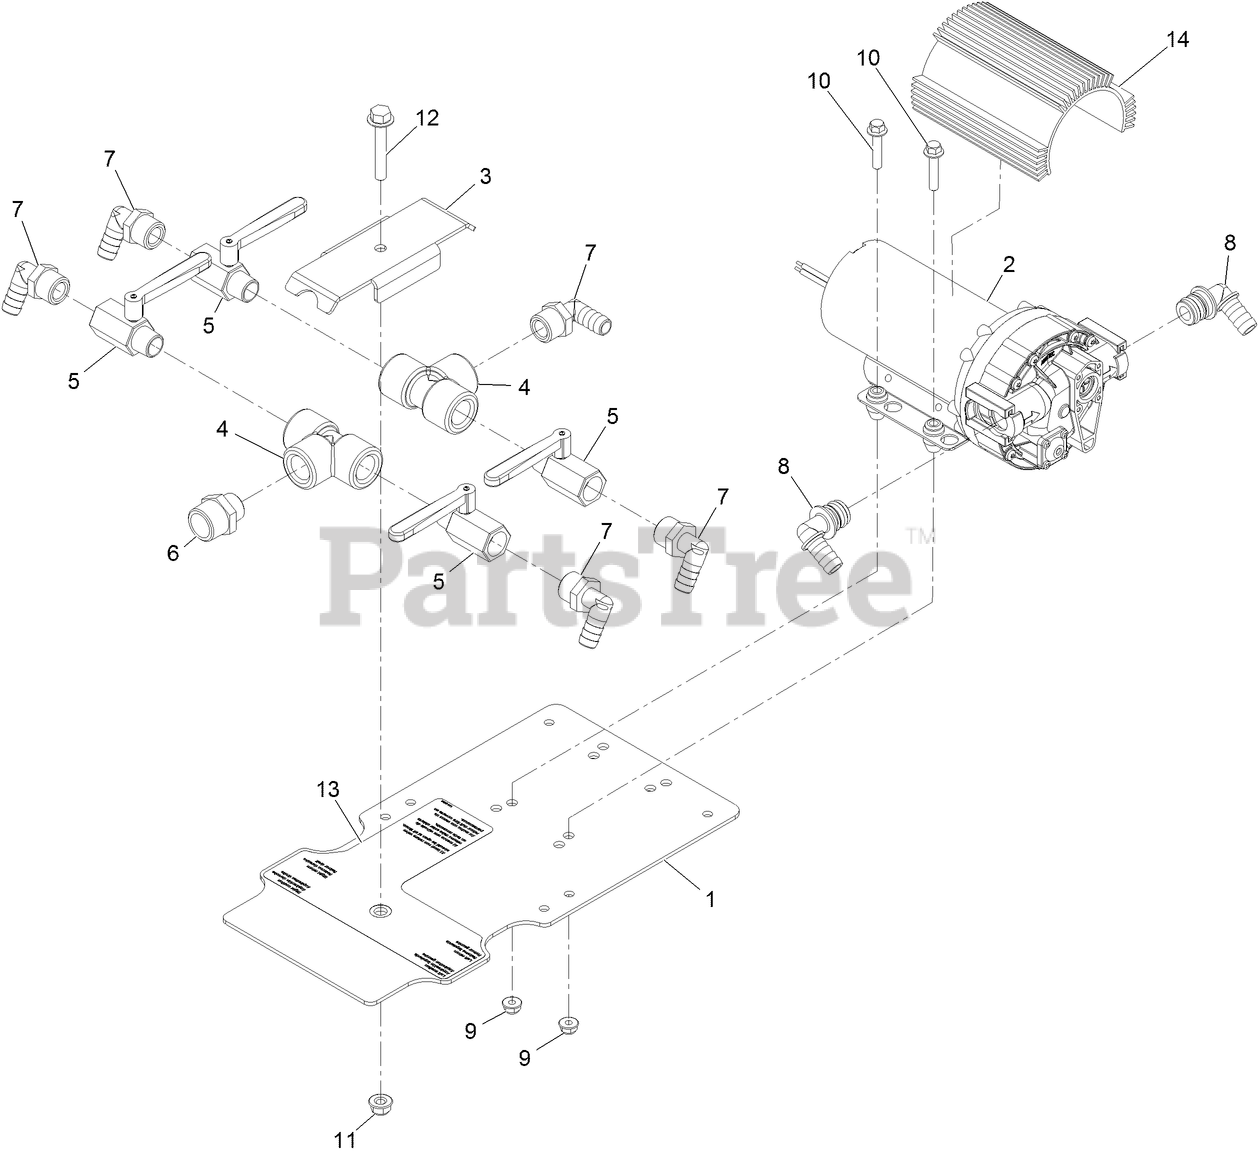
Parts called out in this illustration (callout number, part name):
1	MOUNT-PLATE, LIQUID VALVE
2	PUMP-5.3 GPM
3	PLATE-CLAMP, LIQUID VALVE FITTINGS
5	VALVE-CHROME, 1/2
6	FITTING-NIPPLE
7	FITTING-ELBOW, HOSEBARB
8	FITTING-ELBOW, BARBED
9	NUT-HEX FLANGE
10	SCREW-HHF
11	NUT-HEX FLANGE
12	SCREW-HHF
13	DECAL-VALVE, TANK
14	HEATSINK-3.0"
